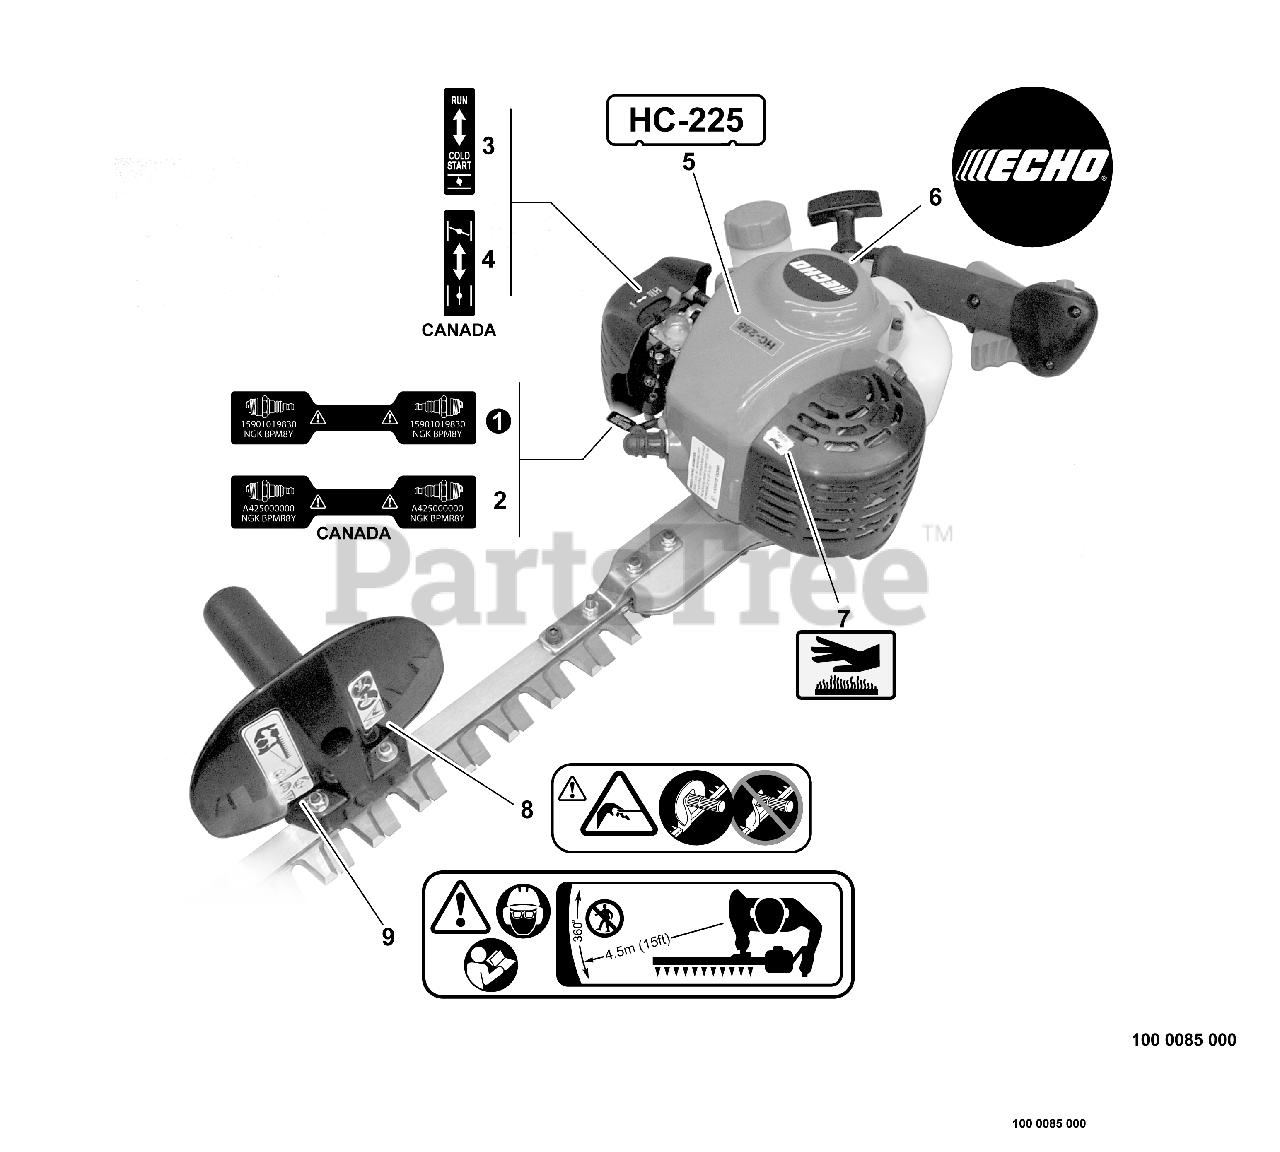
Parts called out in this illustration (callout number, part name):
1	LABEL - SPARK PLUG -- BPM-8Y
2	LABEL - SPARK PLUG -- BPMR-8Y
3	LABEL - CHOKE
4	LABEL - CHOKE
5	LABEL - MODEL HC-225
6	LABEL - ECHO
7	LABEL - HOT SURFACE
8	LABEL - CAUTION
9	LABEL - CAUTION
